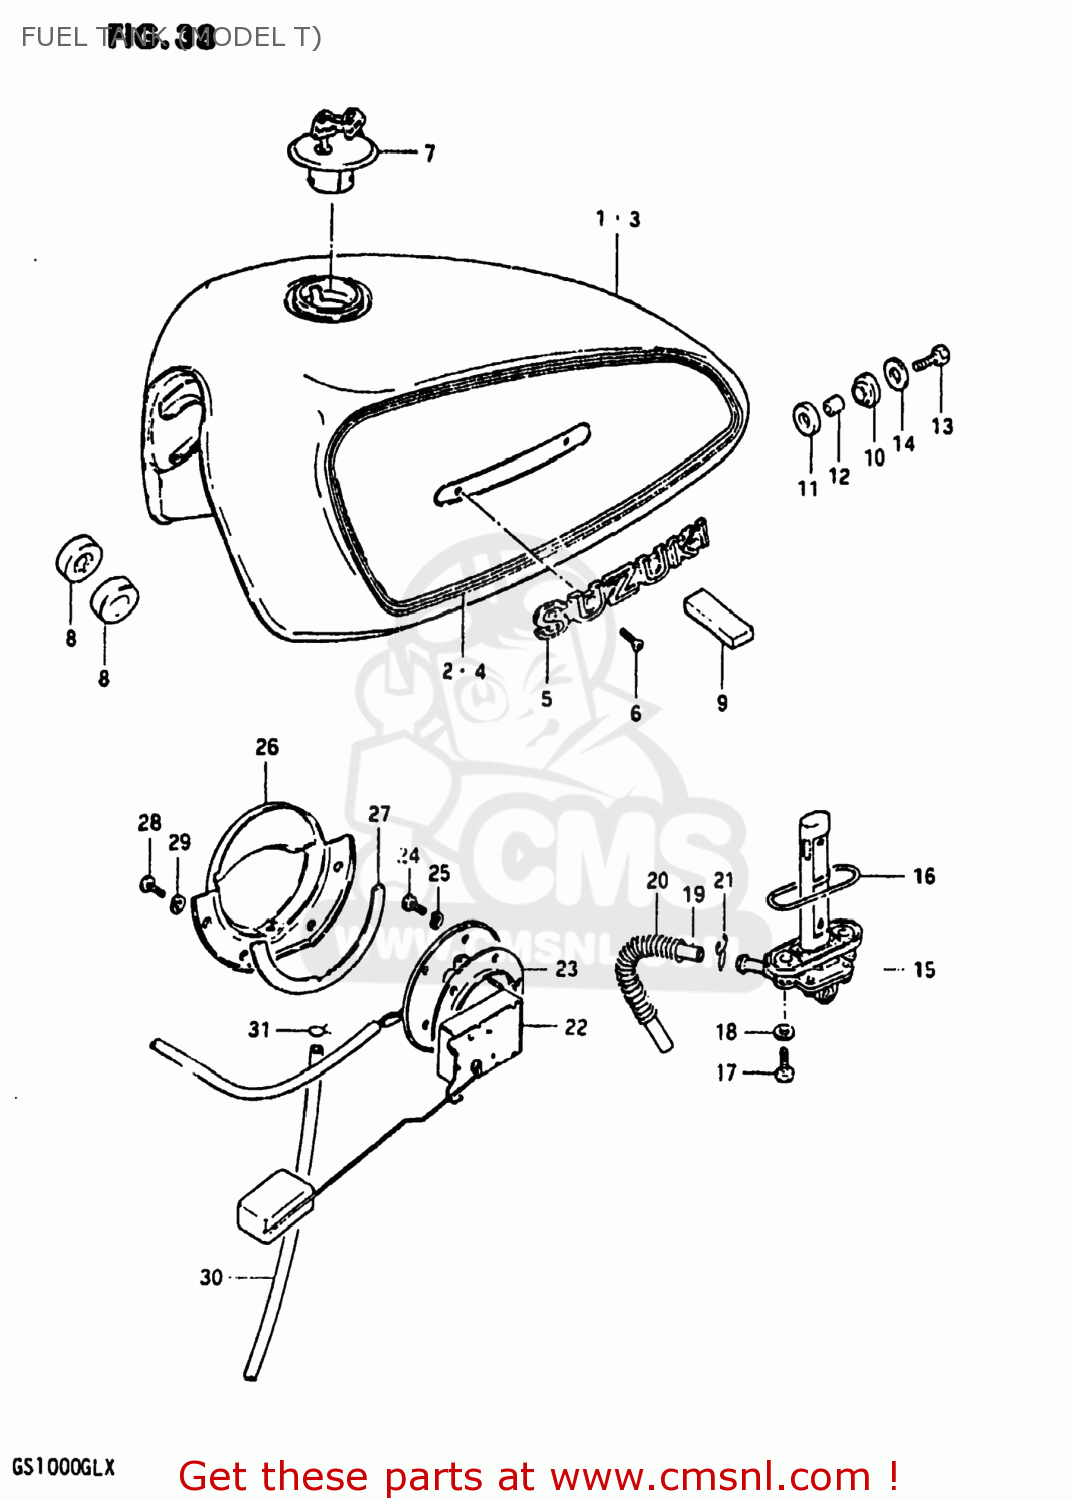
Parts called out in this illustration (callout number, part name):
1	TANK ASSEMBLY,FUEL
2	TAPE SET,FUEL TANK
3	TANK ASSEMBLY,FUEL
4	TAPE SET,FUEL TANK
5	EMBLEM
6	SCREW 3X6
7	CAP SET,FUEL TANK
8	CUSHION
9	CUSHION
10	CUSHION
11	CUSHION
12	SPACER(8.5X12X19)
13	BOLT (8X30)
14	WASHER (8.5X29X1.6)
15	COCK ASSY,FUEL
16	GASKET (NAS)
17	SCREW (6X25)
18	GASKET
19	HOSE
20	SPRING
21	CLIP
22	GAUGE ASSEMBLY,FUEL LEVEL
23	GASKET,FUEL LEVEL GAUGE (NAS)
24	BOLT
25	LOCK WASHER
26	PLATE,FUEL DRAIN
27	GASKET,FUEL DRAIN PLATE (NAS)
28	SCREW
29	LOCK WASHER
30	HOSE,FUEL
31	CLIP
